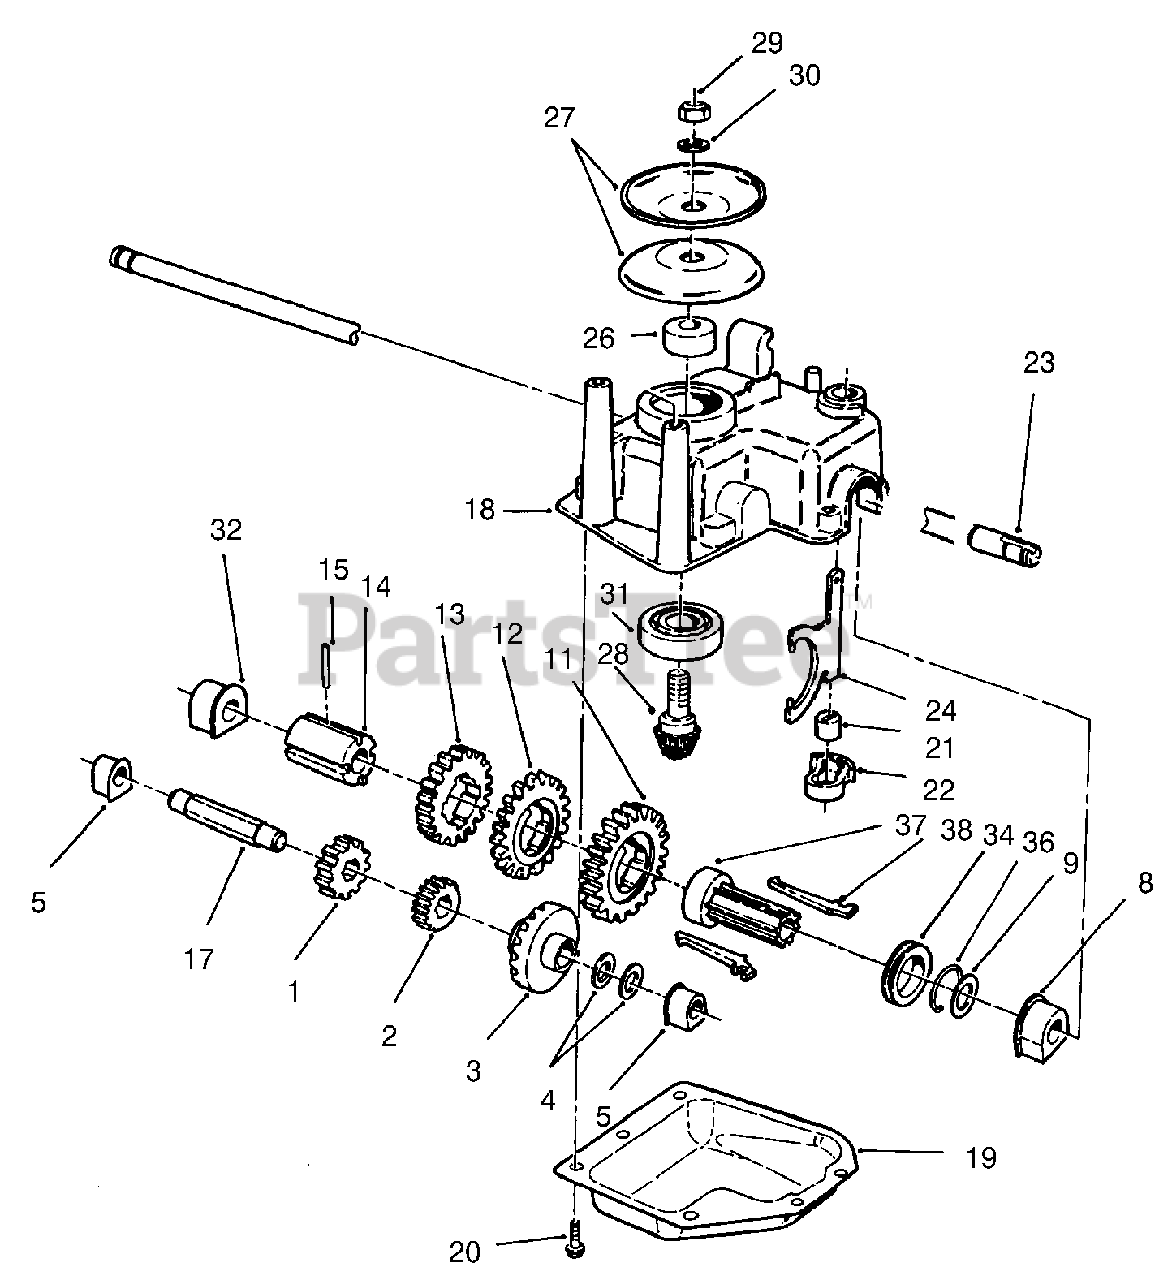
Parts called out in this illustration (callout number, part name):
1	25 T Pinion
2	20 T Pinion
3	Gear-Bevel
4	Washer-Thrust
8	Bushing-Output
11	49 T Gear
12	44 T Gear
13	39 T Gear
14	Sleeve-Gear
15	Pin-Spring
17	Shaft-Intermediate
18	Case-Gear, Upper
19	Cover-Gear Case
20	Screw-Taptite
21	Bushing-Yoke
22	Retainer-Shift Fork
23	Shaft-Output
24	Yoke-Shift
27	Pulley-Half
28	Gear-Bevel, Pinion
29	Nut-Lock, NI
30	Washer-Flat
31	Bearing-Ball
32	Bushing-Output
34	Collar-Shift
36	Clip-Spring
37	Sleeve-Key, Shift
38	Key-Shift
